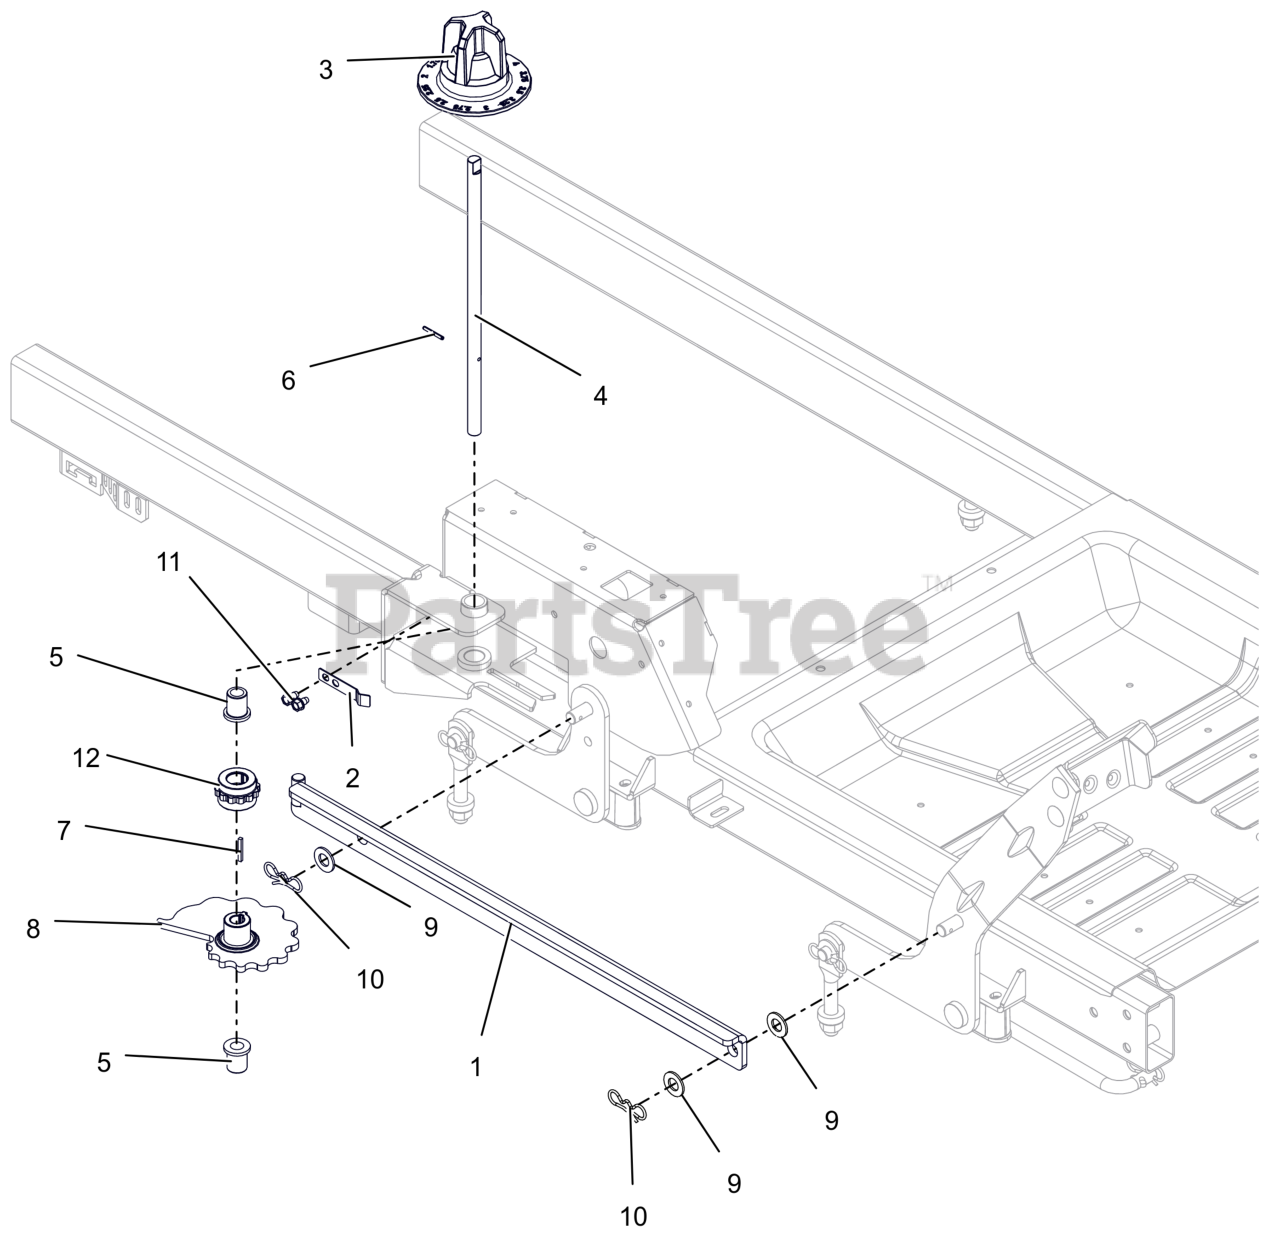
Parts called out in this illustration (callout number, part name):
1	WLDMT, HOC LINK
2	ARM, HOC DETENT
3	KNOB, HOC DIAL
4	SHAFT, HOC CAM IKON
5	BSHG-FLG, .503X.750X.875X1.00
6	PIN-ROLL .125X1.00
7	KEY, 1/8 X 1/8 X 1.0
8	CAM, HOC (PM)
9	WSHR-FL-NYL .518X1.000X.080
10	PIN, BOWTIE .091X1.875 ZCC
11	SCR,TAP .25-20X.375 HWH TR ZCC
12	GEAR, HOC INDEX
